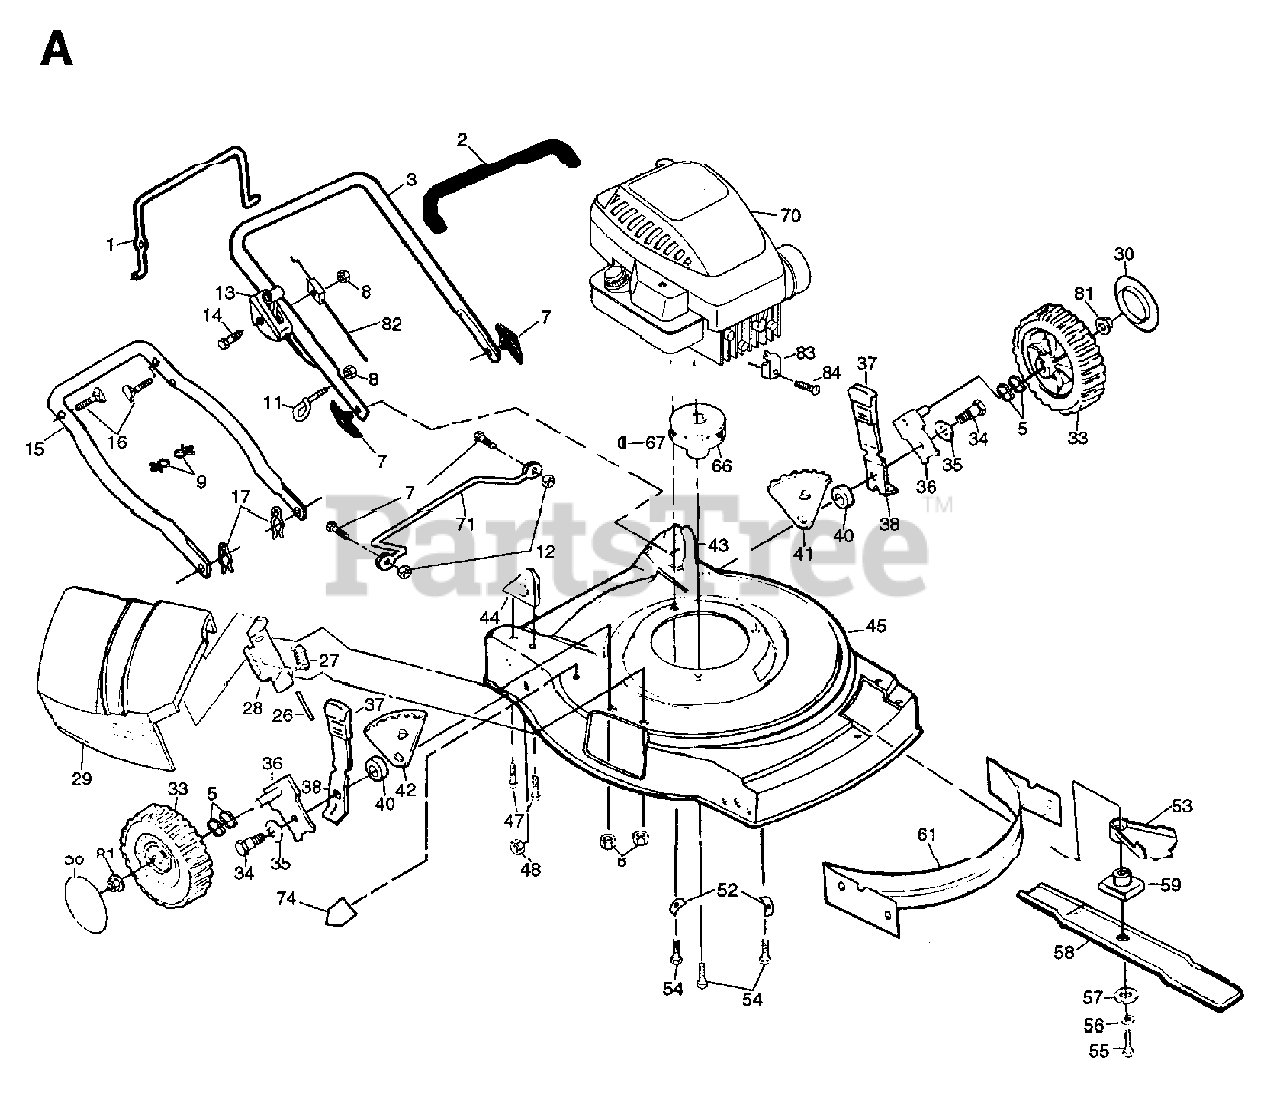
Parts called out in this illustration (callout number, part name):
1	BAIL.CNTRL.SRD.CM
2	HANDLE GRIP
3	UPPER HANDLE
5	WAVE WASHER
7	HANDLE KNOB
8	NUT
9	CLIP CABLE SNAP
11	ROPE GUIDE
13	THROTTLE CONTROL
14	SCREW 1/4-20 X 2.12
16	HANDLE BOLT
17	HAIRPIN COTTER
26	ROD.HINGE.COMBI-C
27	SPRING PM
28	BRACKET PM
33	WHEEL.8X2.PR.LP.RAD.GREY
34	BOLT
35	BELLEVILLE WASHER
36	AXLE ARM
37	SELECTOR KNOB
40	RP SPACER HT ADJ
43	HDLE BRKT ASSY LH
44	HDLE BRKT ASSY RH
47	SCREW 5/16-18
48	LOCKNUT PM
53	DEBRIS SHIELD
54	BOLT 3/8-16X1-1/8
55	SCREW, HEX HD 3/8-24 X 1-3/8
56	LOCKWASHER
57	WASHER,HARDEN
58	BLADE 22"
59	RP BLADE ADAPTOR
66	ENGINE.PULLEY.FWG
67	HI PRO KEY PM
74	DECAL MOWER CUT/FINGER
81	HEX FLANGE LOCKNT
82	ENGINE ZONE CONTROL CABLE
84	SCREW.HEX.HEAD.WASHER.10-16
